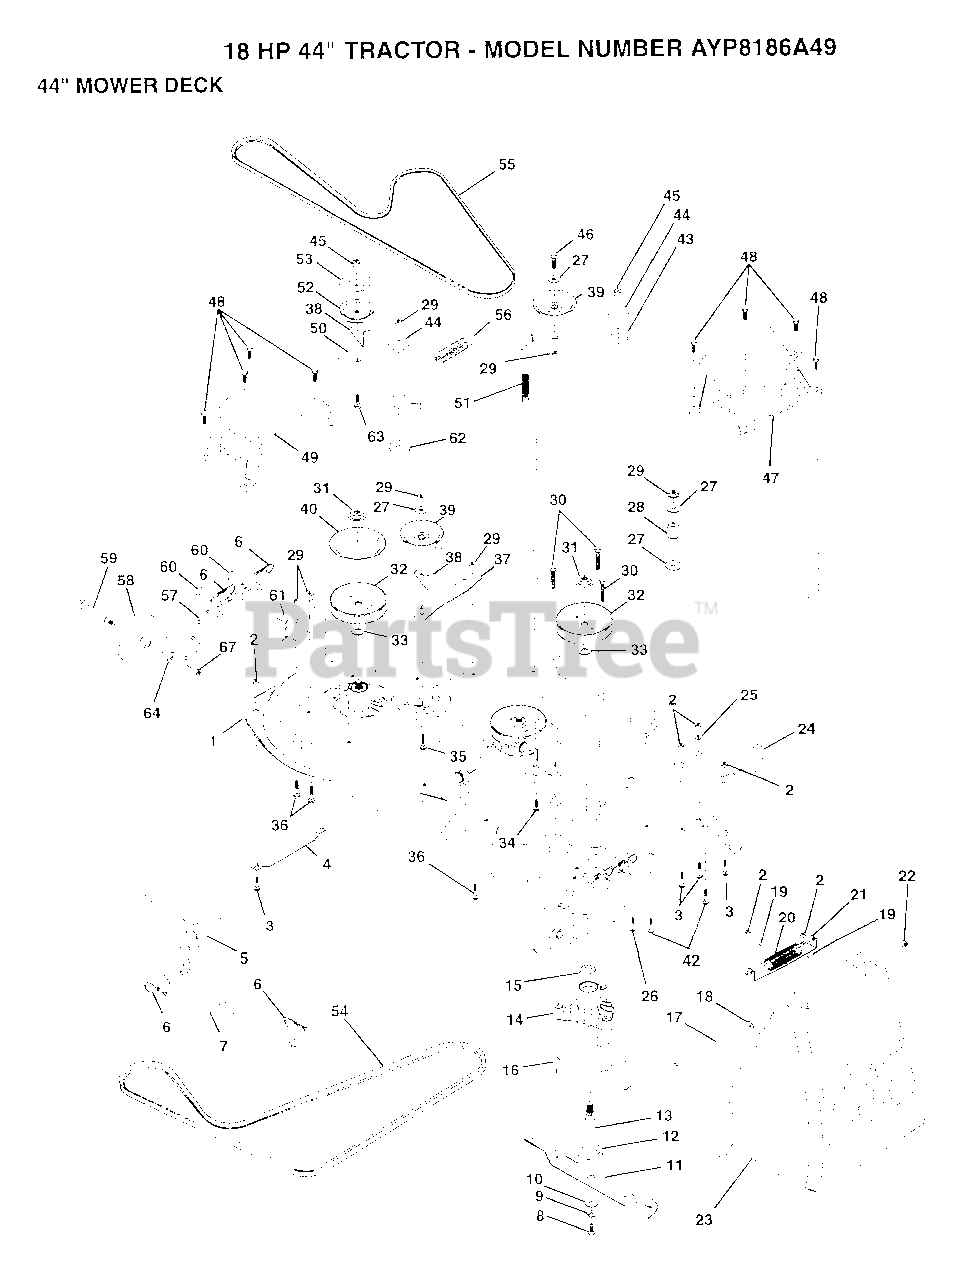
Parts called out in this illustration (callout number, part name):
2	NUT
4	RUNNER-LH M
5	BRKT.ASM.SW.44/50
8	BLADE BOLT
10	WASHER.HARD.BLADE
11	"BLADE.44"" HIPERF"
12	BEARING.BALL
13	SHAFT.ASM.W/BRNG
14	HOUSING.MAND.44.V
15	BEARING
17	ROD-HINGE T
18	WASHER
19	CAP-SLEEVE LT
20	SPRING TORSION
21	BRKT DEFLECTOR
22	NUT PUSH M
23	DEFLECTOR SHIELD
24	RUNNER.RH
25	WASHER M
26	BOLT
27	WASHER
29	NUT
33	WASHER
34	BOLT.3/8-14X1.25
35	BOLT
36	BOLT D
37	STIFFENER.ARM.IDL
39	FLAT IDLER PULLEY
40	"PULLEY.DRIVEN.44"""
42	BOLT
43	"ARM.IDLER.SEC.44"""
44	SPACER RETAINER
47	"COVER.MAND.RH.44"""
48	SCREW.1/4-20X5/8
49	COVER.MANDREL.LH
50	ARM.IDLER.PRIMARY
51	"SPRING.SEC.44""VEN"
52	PULLEY.IDLER.VGRO
53	SHIELD.IDLER.44.V
54	V-BELT.PRIM.78.5.
55	BELT-V.88.12.MW
56	SPRING.EXT.DECK.
57	BAR.ASM.GUAGE.WHL
58	WHEEL GAGE DONUT
59	BOLT.SHOULDER
60	PIN.CLEVIS
61	BRACKET.GUAGE.WHL
62	HARDENED WASHER
63	BOLT.3/8-16X1.50
64	WASHER
67	LOCKNUT
